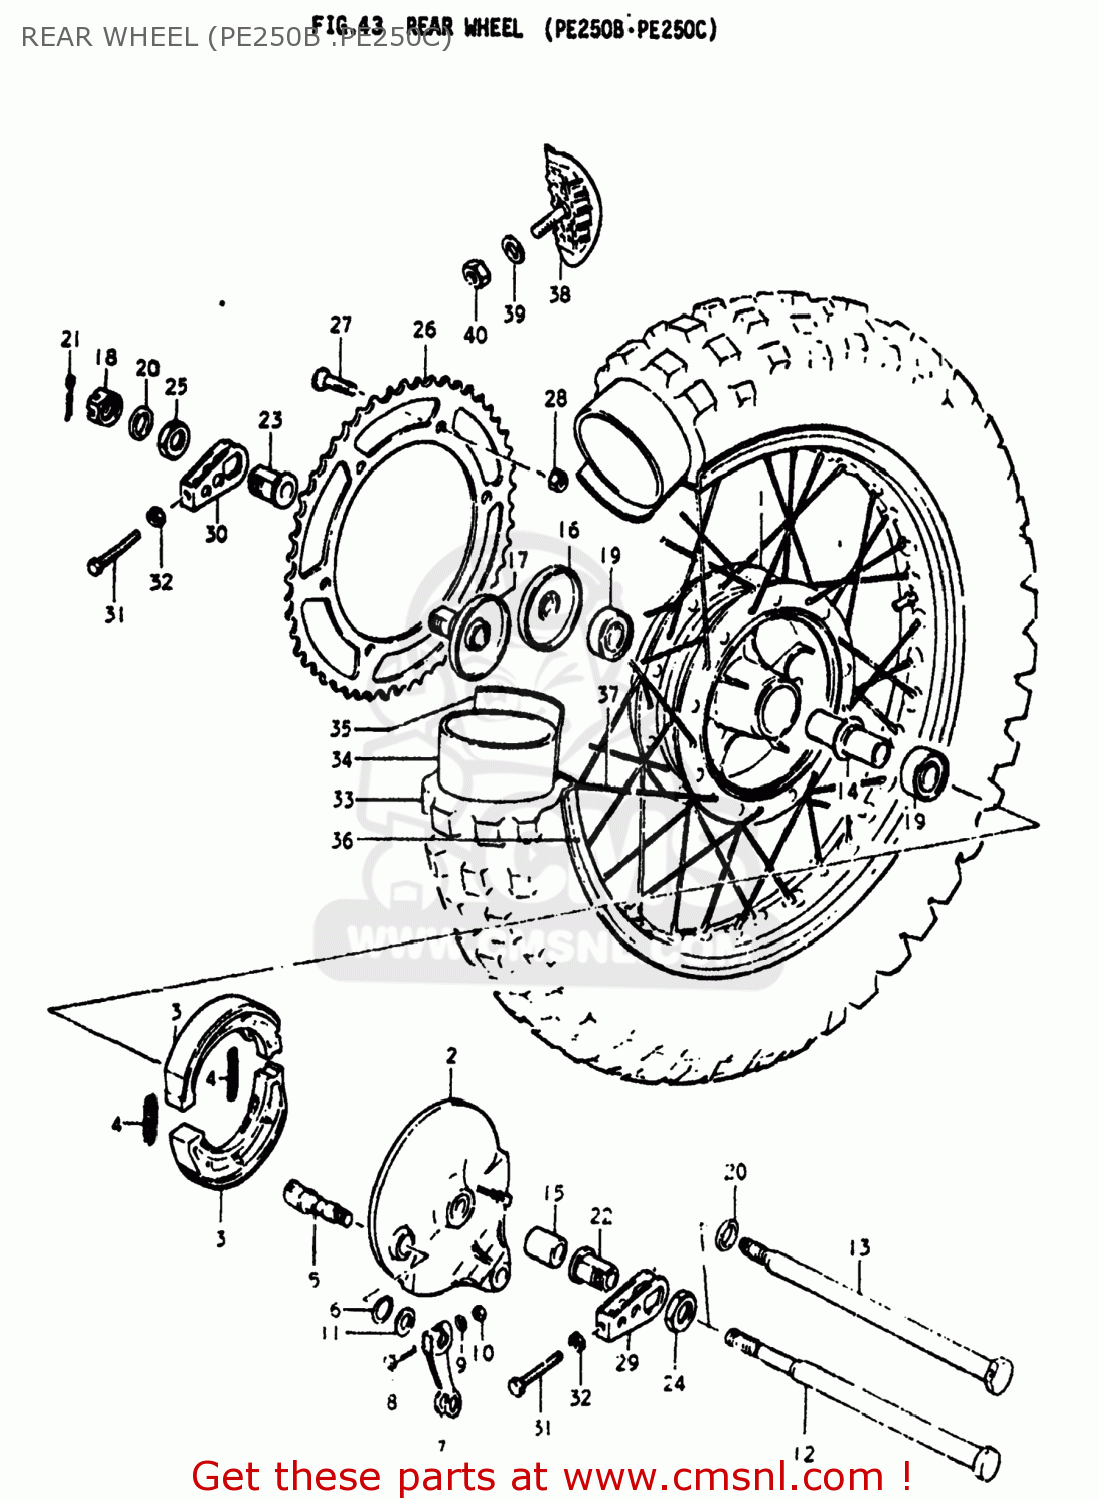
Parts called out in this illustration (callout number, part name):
1	HUB REAR
2	PANEL,REAR HUB
3	SHOE,BRAKE
4	SPRING
5	CAM,FRONT BRAKE
6	O-RING,BOSS
7	LEVER,REAR BRAKE CAM
8	BOLT
9	WASHER
10	NUT
11	WASHER (15X24X1.6)
12	AXLE,REAR
13	AXLE,REAR
14	SPACER,REAR HUB BEARING
15	SPACER
16	SPACER,REAR AXLE
17	SPACER,REAR AXLE
18	NUT
19	BEARING
20	WASHER (17X30X3.2)
21	PIN 30X40
22	SPACER,CHAIN ADJUSTER
23	SPACER,CHAIN ADJUSTER
24	NUT
25	NUT
26	SPROCKET,REAR
27	SCREW
28	NUT
29	ADJUSTER,CHAIN
30	ADJUSTER,CHAIN
31	BOLT
32	NUT
33	TIRE
34	TUBE ASSEMBLY,WHEEL,INNER
35	PROTECTOR,WHEEL,INNER
36	RIM,REAR WHEEL
37	SPOKE SET,REAR
38	STOPPER,BEAD
39	WASHER
40	NUT
